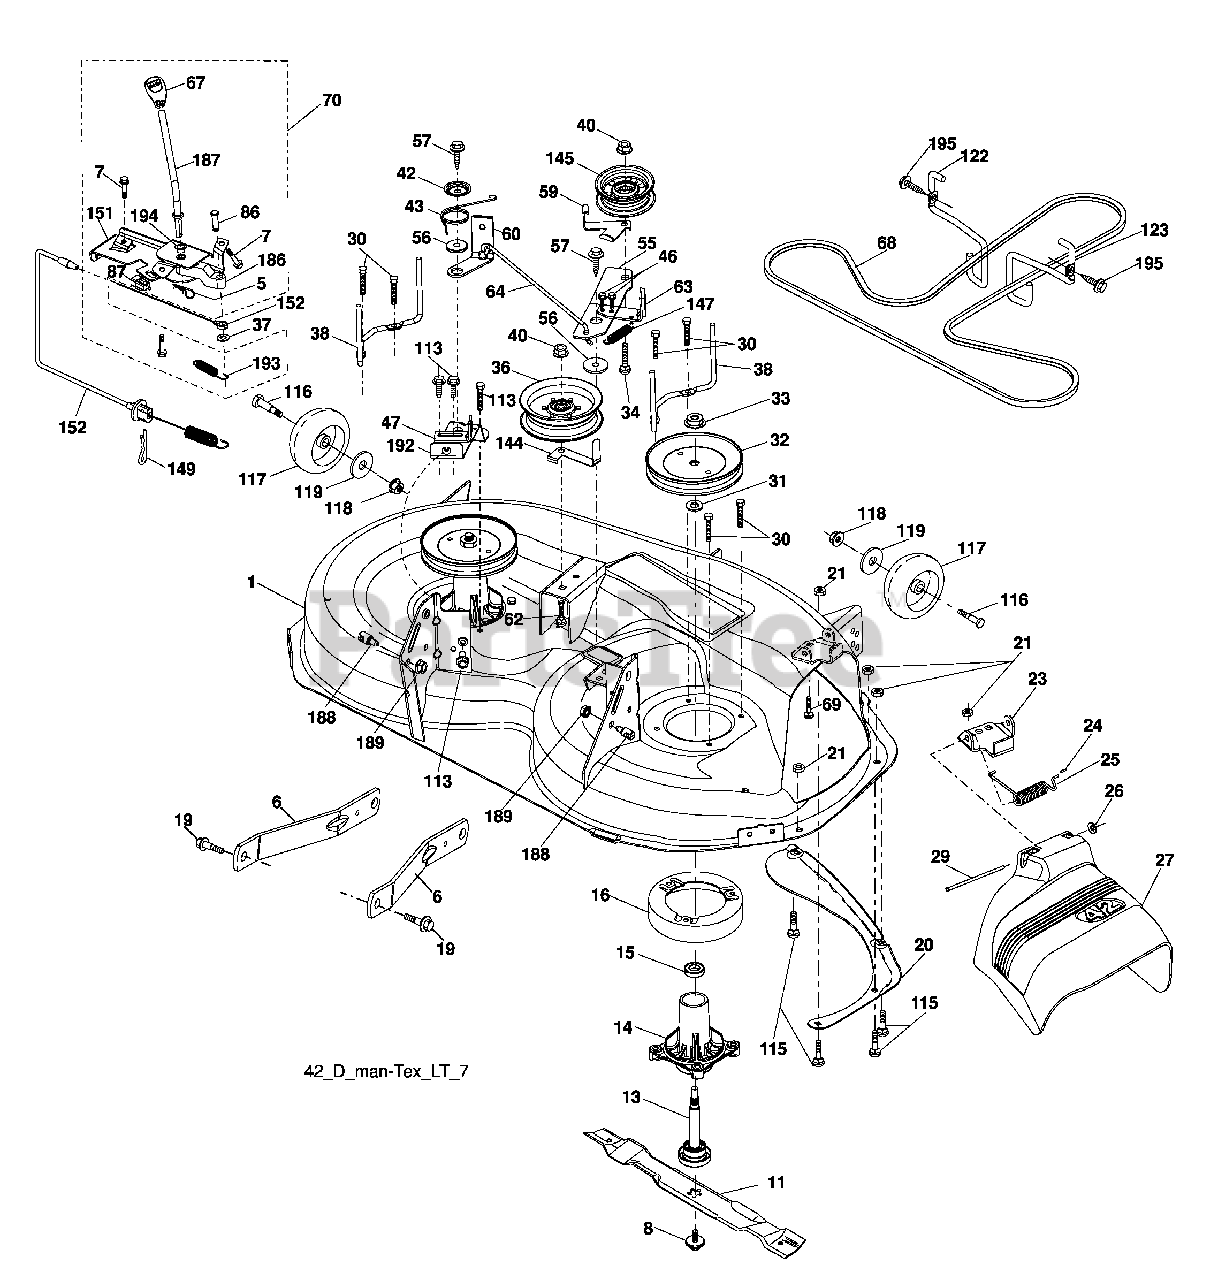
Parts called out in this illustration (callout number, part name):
1	Mower Housing
5	Retainer Spring
6	Arm Suspension
7	Screw 10 x 3/4 Single Lead Hex
8	Bolt/Washer asm 7/16-20 unf
11	Blade, 42" Hi-Lift
13	Shaft Assembly, Mandrel
14	Housing, Mandrel
15	Bearing, Ball, Mandrel
16	Stripper, Mower Deck
19	Bolt, Shoulder
20	Baffle, Vortex
21	Nut, Crownlock 5/16-18 unc
23	Bracket, Deflector
24	Cap, Sleeve
25	Spring, Torsion, Deflector
27	Shield, Deflector
29	Rod, Hinge
30	Screw Thdrol Rolling Wsh Hd
31	Washer, Spacer
32	Pulley, Mandrel
33	Nut, Toplock, Flanged
34	Bolt Carr Sh. 3/8-16 x 1-1/2 Gr. 5
36	Pulley, Idler, Flat
37	Washer
38	Keeper Belt LH Mandrel
40	Nut, Lock Flg. 3/8-16 unc
42	Spring Torsion Brake
43	Spring Torsion Retainer
46	Screw Thd Roll 1/4-20 x 5/8
47	Bracket Clutch Cable
55	Arm, Idler
56	Spacer, Retainer
59	Screw 3/8-16 x 1
60	Guard, Tuv Idler
62	Arm Brake Mower
63	Bolt Rd Hd Sq Nk 3/8-16 unc x 2
64	Arm Brake Mower
67	Link Brake
68	Handle Clutch Cable
69	V-Belt
70	Bolt
86	Clutch Asm Manual
87	Pin Attachment Cable
113	Switch Interlock Clutch Cable
115	Screw 5/16-18
116	Bolt Carr. 5/16-18 x 5/8
117	Bolt, Shoulder
118	Wheel, Gauge
119	Nut, Crownlock 3/8-1
122	Washer 13/32 x 7/8 x 14 Ga.
123	Keeper Belt Engine LH
144	Keeper Belt Engine RH
145	Keeper Belt
147	Pulley Idler
149	Spring Return
151	Retainer Spring
152	Bracket
186	Manual Clutch Cable
187	Arm Actuator
188	Lever Control Clutch
189	Stud Fastener
192	Nut Lock Hex Flange
194	Bracket Brake Stand LH
195	Bearing Control Lever Clutch
197	Screw 3/8-16 x 3/4
